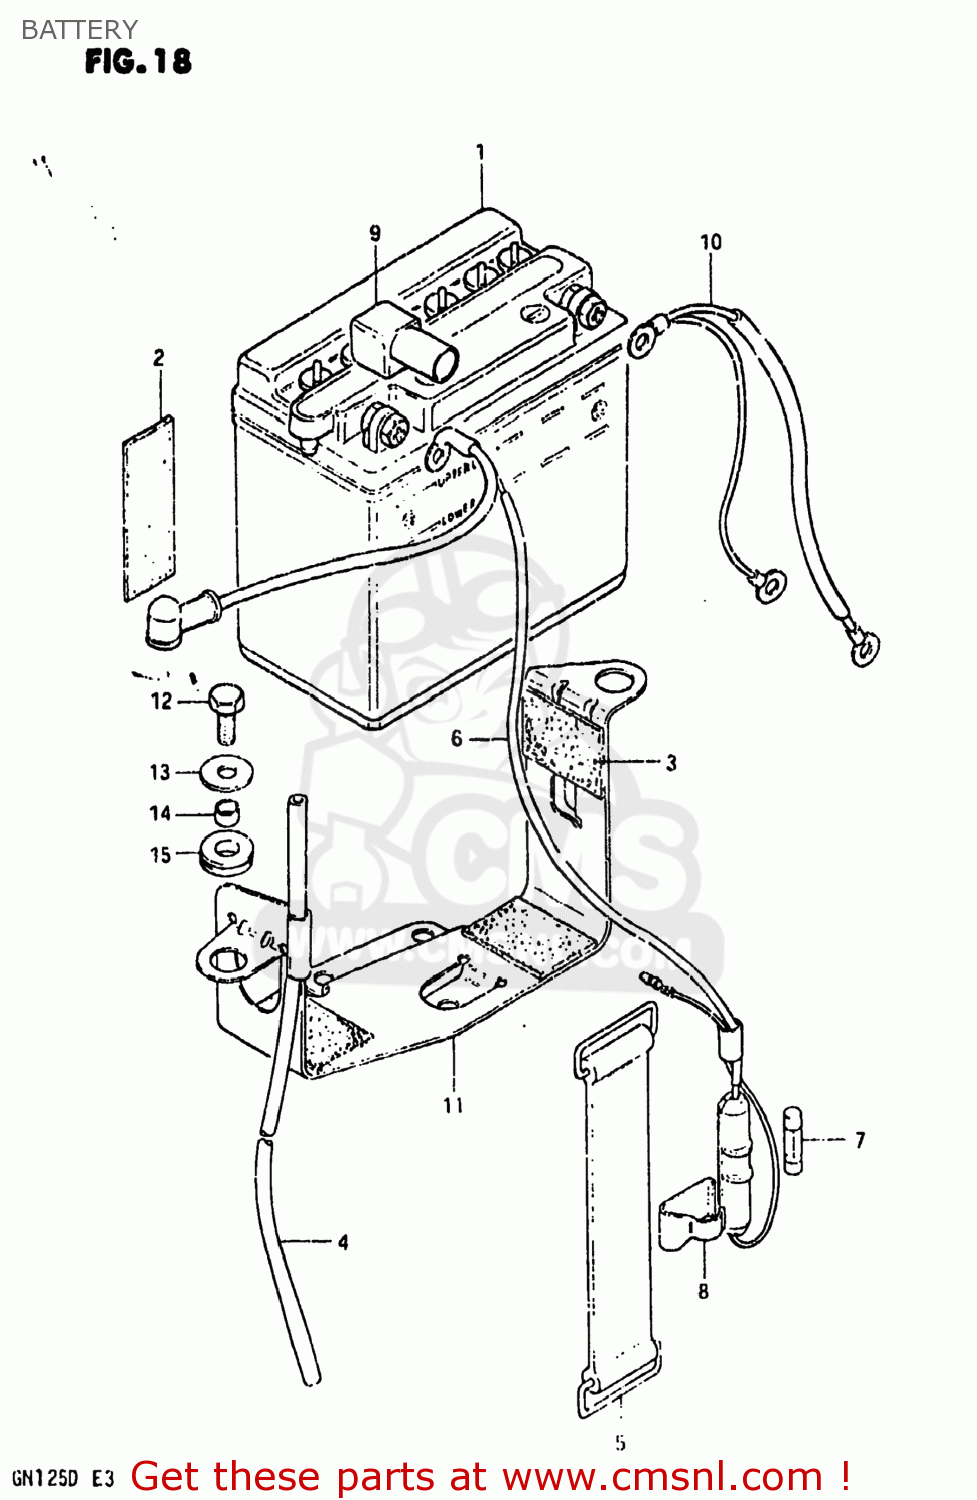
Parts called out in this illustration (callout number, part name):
1	BATTERY ASSEMBLY (12V)
2	PROTECTOR(170X95X3.0)
3	PROTECTOR(170X95X3.0)
4	HOSE,BATTERY EXHAUST
5	BAND
6	FUSE CASE AND PLUS CABLE
7	FUSE(15A)
8	HOLDER,FUSE CASE
9	CAP,TERMINAL
10	LEAD WIRE,BATTERY(-)
11	HOLDER,BATTERY
12	BOLT, UPPER
13	WASHER (6.5X20X1.2)
14	SPACER(6.1X9X7.5)
15	CUSHION
